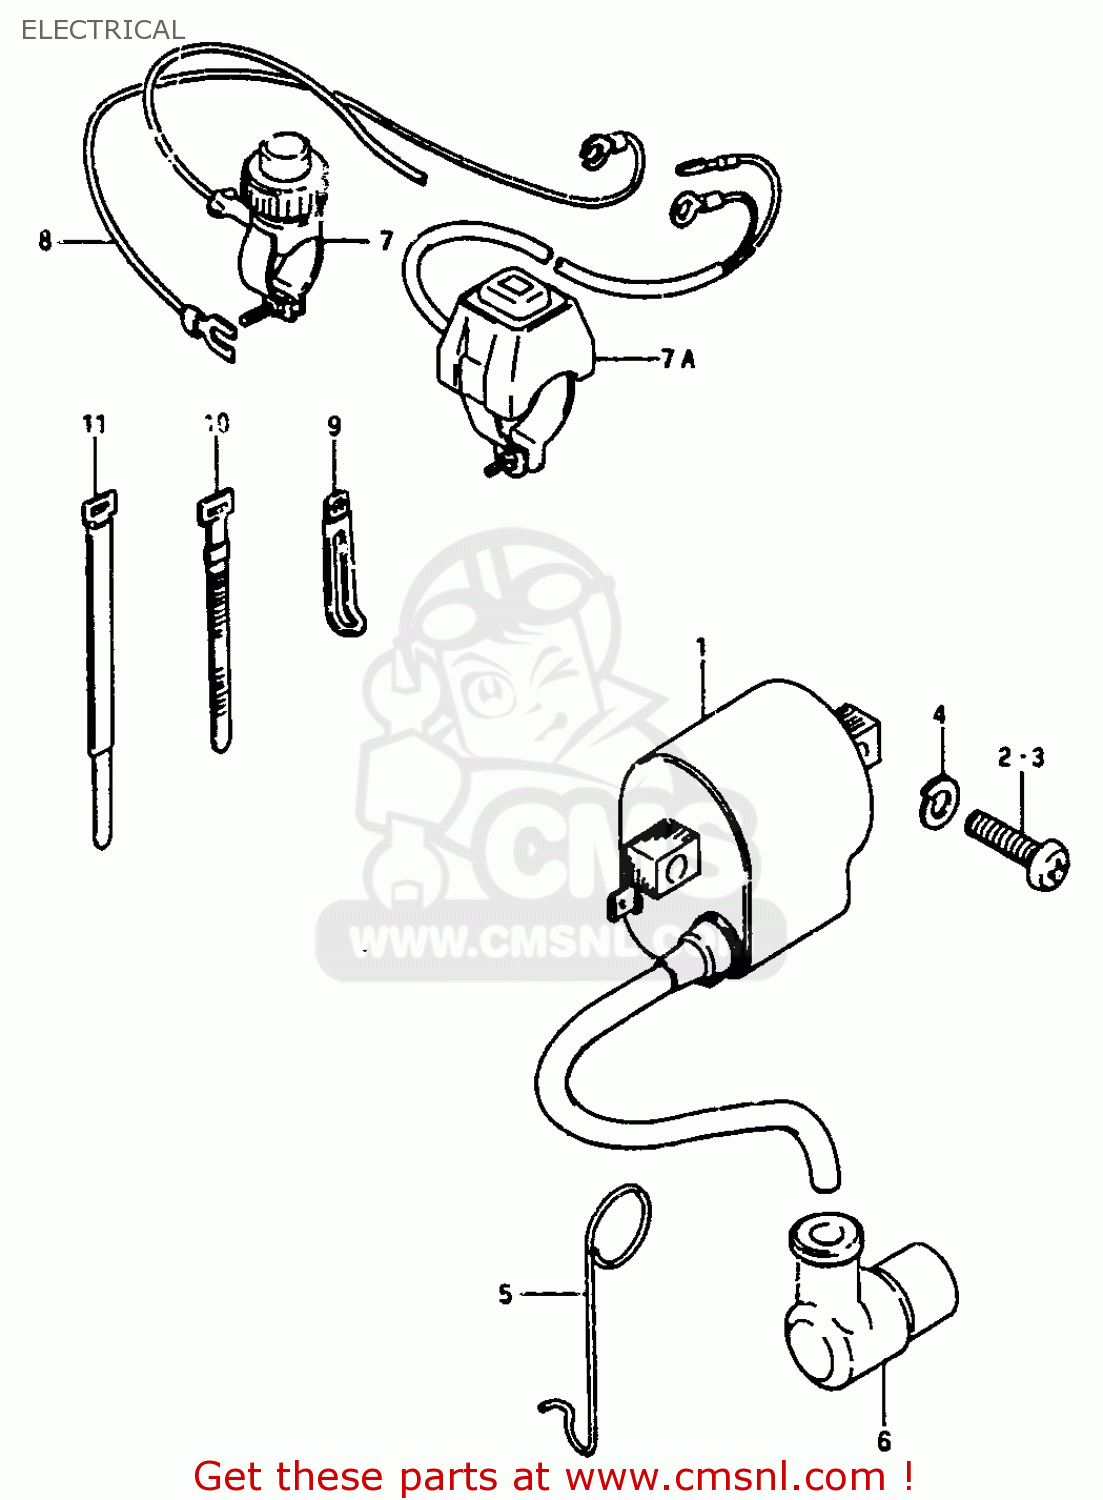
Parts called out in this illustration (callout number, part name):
1	COIL ASSEMBLY,IGNITION
2	SCREW
3	SCREW
4	WASHER,LOCK
5	CLIP
6	CAP,SPARK PLUG
7	SWITCH ASSEMBLY
7A	SWITCH ASSEMBLY
8	WIRE
9	CLAMP
10	CLAMP(L:120)
11	CLAMP
